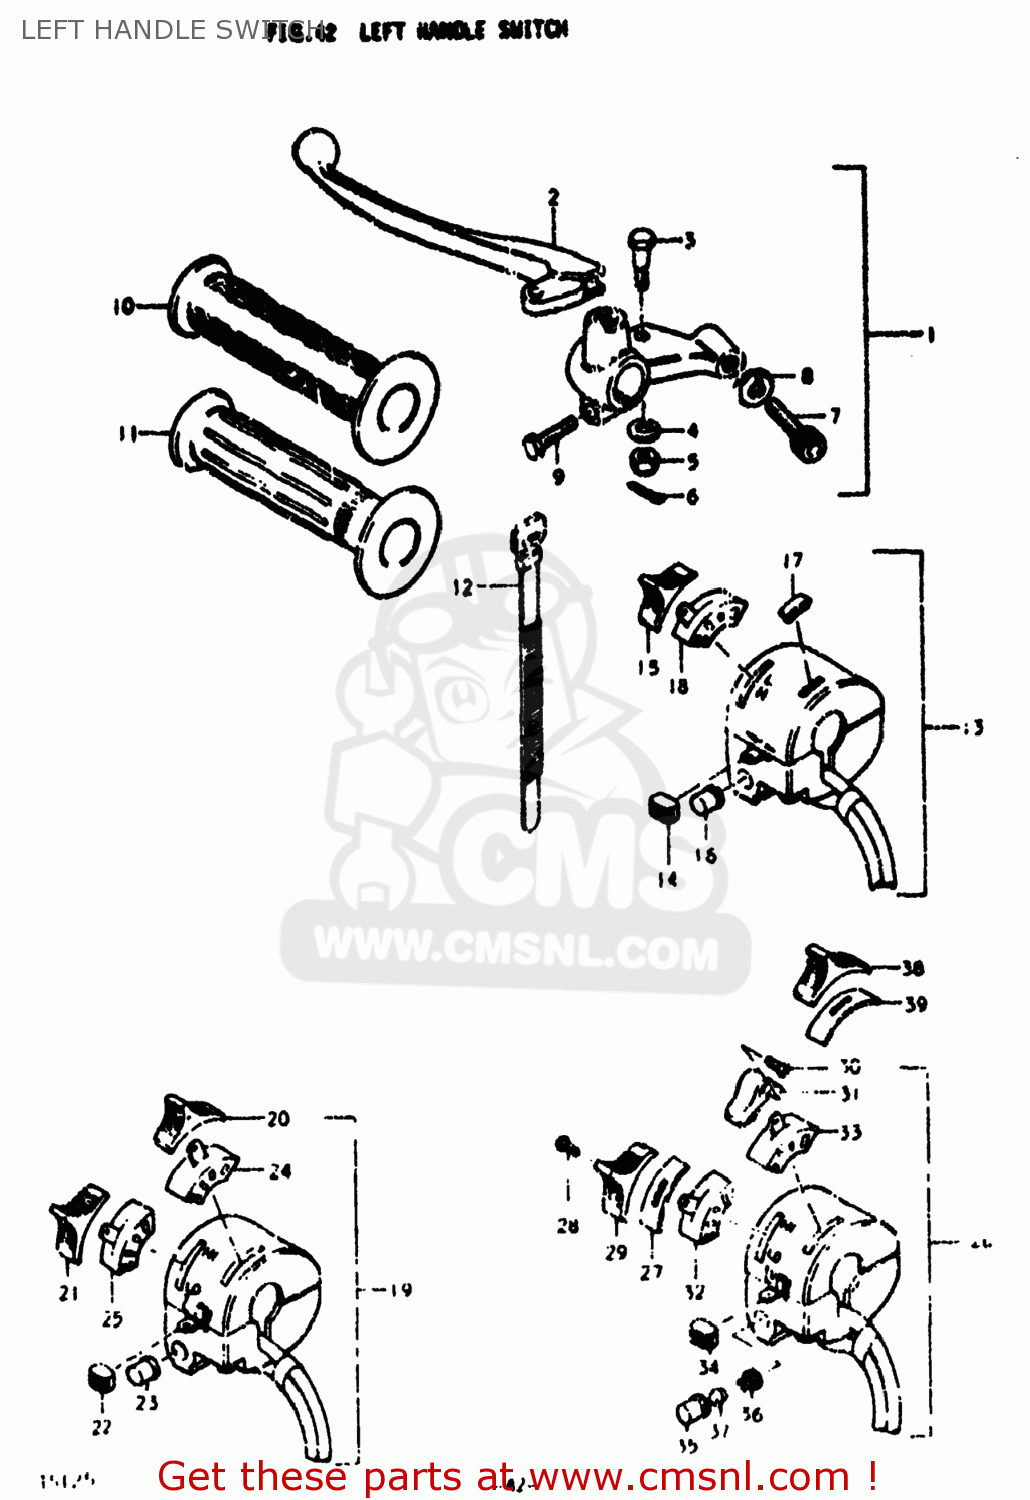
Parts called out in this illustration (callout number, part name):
1	LEVER ASSEMBLY
2	LEVER,CLUTCH
3	BOLT,LEVER
4	WASHER,LOCK
5	NUT,LEVER FITTNG
6	COTTER PIN
7	ADJUSTER,CABLE
8	NUT,CABLE ADJUSTER
9	BOLT
10	GRIP
11	GRIP,L
12	CLAMP(L:120)
13	SWITCH ASSEMBLY,HANDLE
14	KNOB,HANDLE SWITCH
15	KNOB,HANDLE SWITCH
16	BUTTON, HORN
18	DIMMER SWITCH BLOCK
19	SWITCH ASSEMBLY,HANDLE
20	KNOB,HANDLE SWITCH
21	KNOB,HANDLE SWITCH,UPPER
22	KNOB,HANDLE SWITCH
23	BUTTON, HORN
25	SLIDING BLOCK, DIMMER SWITCH
26	SWITCH ASSEMBLY,HANDLE,LEFT
27	PLATE,DIMMER KNOB
28	SCREW, DIMMER
29	KNOB,HANDLE SWITCH,UPPER
30	SCREW
31	KNOB
32	SLIDING BLOCK, DIMMER SWITCH
34	KNOB,HANDLE SWITCH
35	BUTTON, HORN
36	SPRING,BUTTON
37	PLATE,HORN BUTTON
38	KNOB,HANDLE SWITCH
39	PLATE,LIGHTING KNOB
